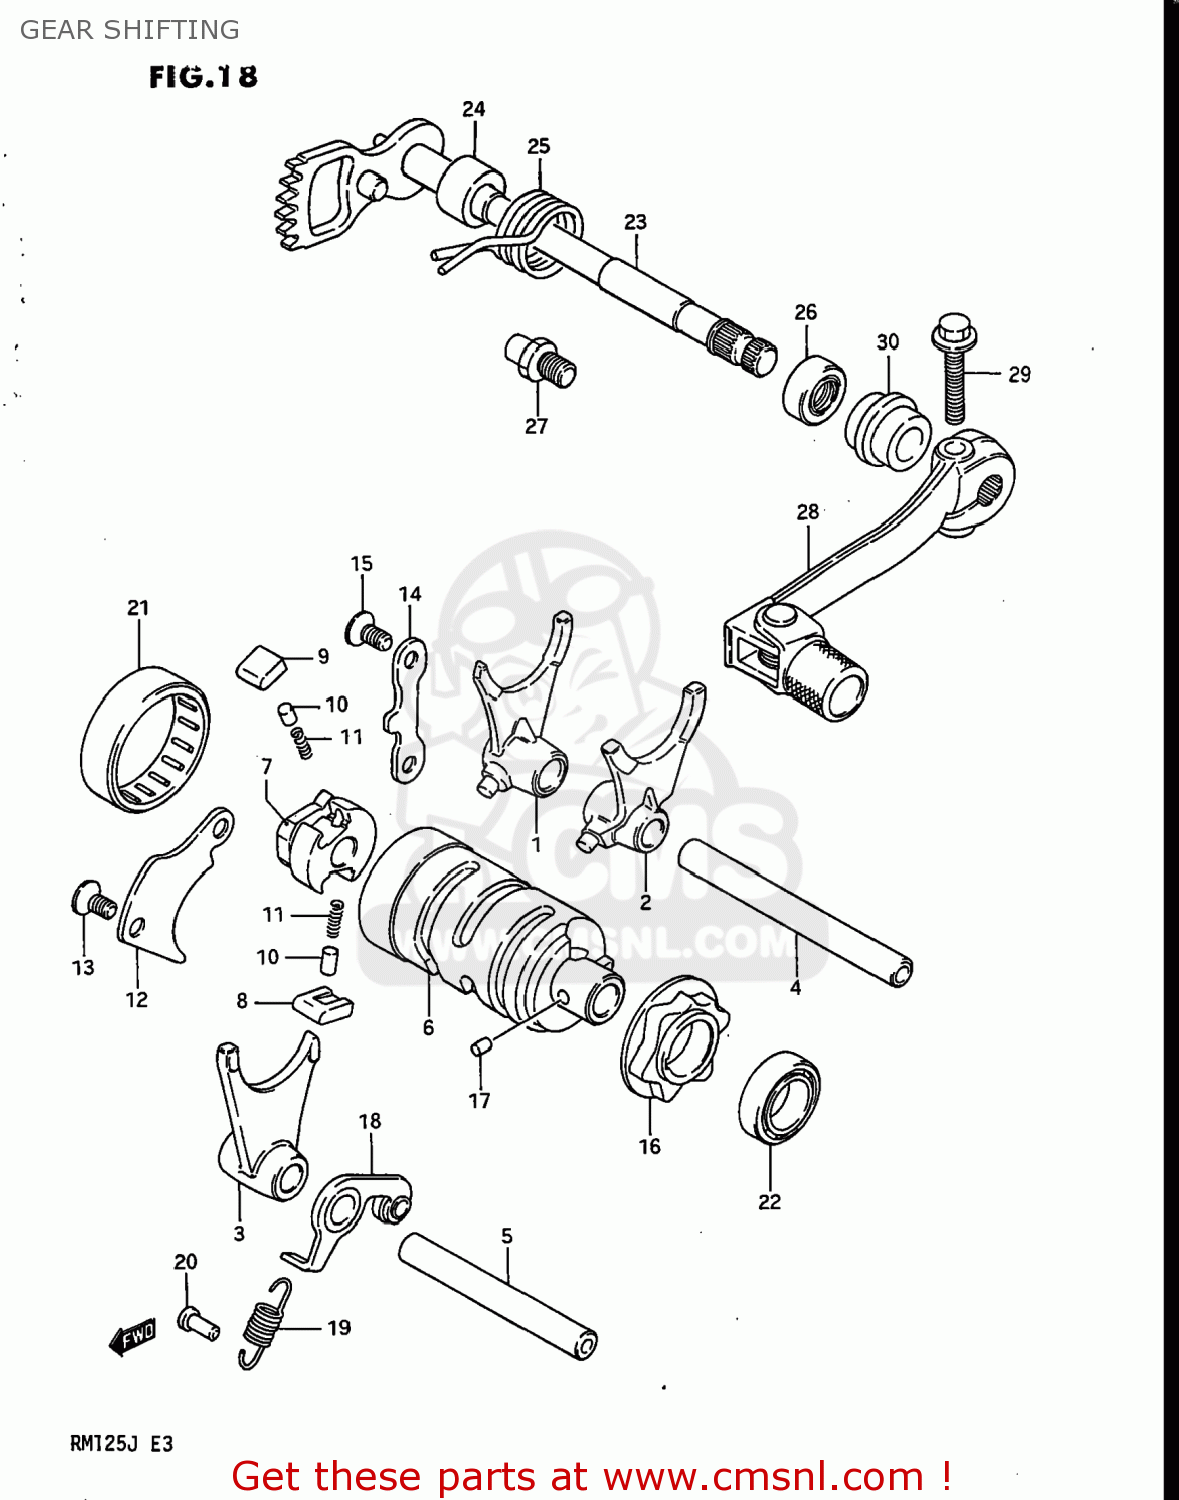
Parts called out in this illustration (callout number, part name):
1	FORK,GEAR SHIFT NO.1
2	FORK,GEAR SHIFT NO.2
3	FORK,GEAR SHIFT NO.3
4	SHAFT,GEAR SHIFT FORK
5	SHAFT,GEAR SHIFT FORK
6	CAM,GEAR SHIFT
7	GEAR,GEARSHIFT CAM DRIVE
8	PAWL,GEAR SHIFT NO.1
9	PAWL,GEAR SHIFT NO.2
10	PIN(5X8)
11	SPRING
12	LIFTER,GEAR SHIFT PAWL
13	SCREW
14	GUIDE,GEAR SHIFT CAM
15	SCREW
16	PLATE,GEAR SHIFT CAM STOPPER
17	PIN
18	STOPPER,GEAR SHIFTING
19	SPRING
20	RIVET
21	BEARING
22	BEARING
23	SHAFT COMP,GEAR SHIFTING
24	SPACER(12X20X15.3)
25	SPRING
26	OIL SEAL
27	STOPPER,GEAR SHIFT CAM
28	LEVER ASSY,GEAR SHIFT
29	BOLT
30	CUSHION
